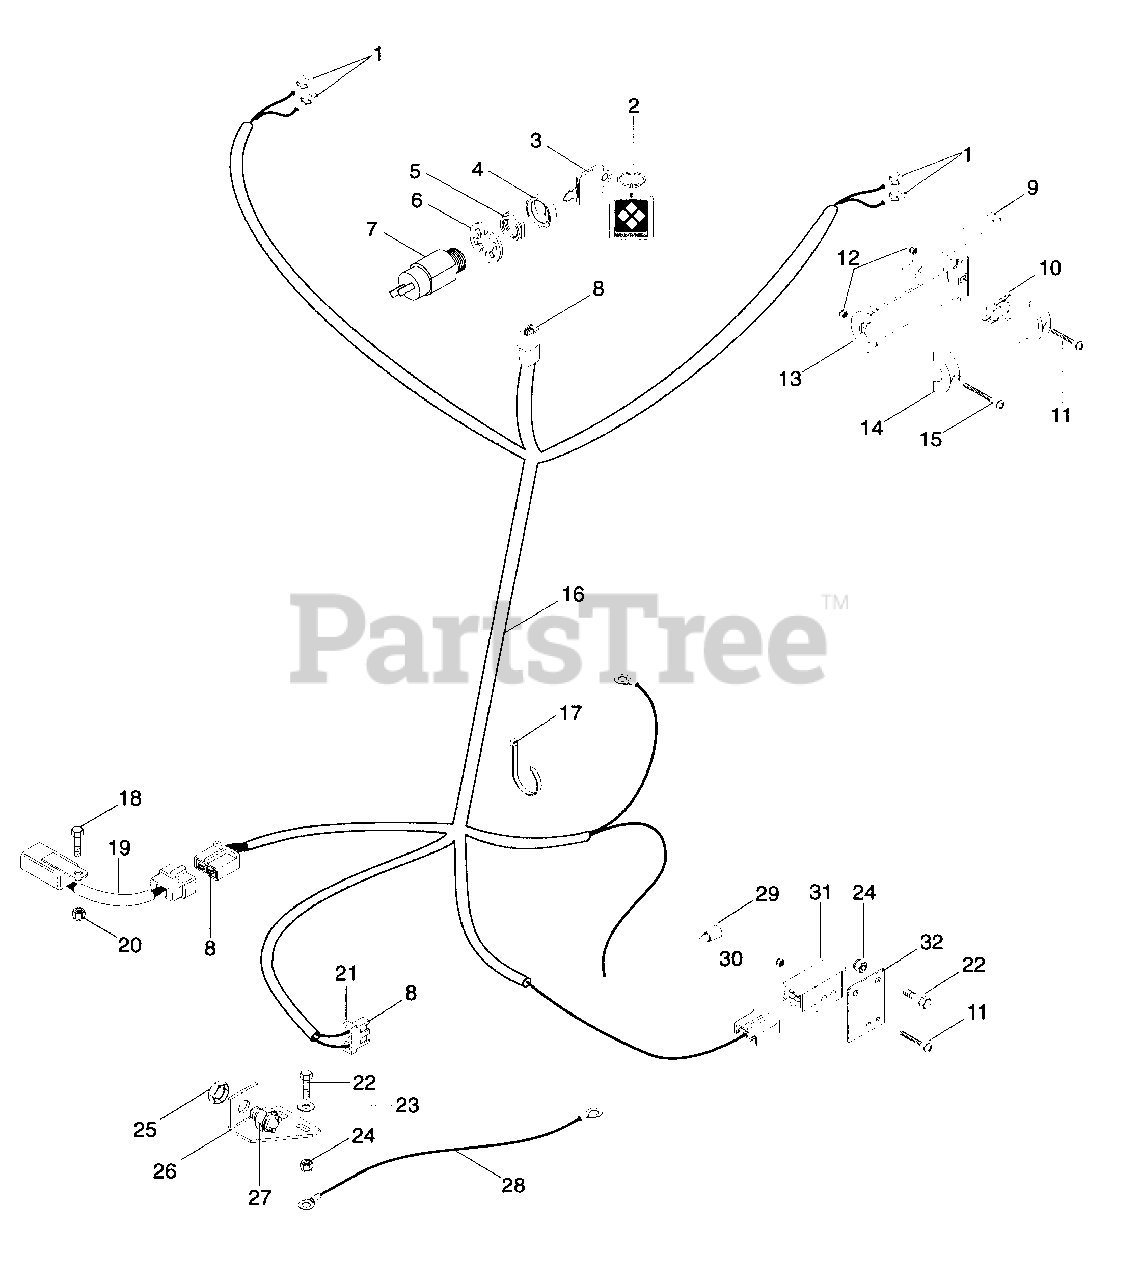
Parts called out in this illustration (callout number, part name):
1	Terminal, Female
2	Key Chain
3	Ignition Switch Key
4	Cap-Ignition Switch
5	Nut-Panel .625-32
6	Washer-Lock .625
7	Switch
8	Terminal
9	Lever
10	Switch
11	Screw-Machine 10-24 x .625
12	Nut-Locking 10-24 Nylon
13	Handle, Right Hand
14	Handle, Left Hand
15	Screw-Machine 10-24 x 1.50
16	Wire Harness, Pro-300 Recoil
17	Tie Wrap, Black
18	Bolt-Hex .25-20 x .75 Grade 5
19	Module
20	Nut-Locking-Nylon .250-20 w/Insert Grade 2
21	Connector, 2-Wire Switch
22	Bolt-Hex .25-20 x.75 Grade 5
23	Washer-Flat-Steel .281 x .625 x .065
24	Nut-Locking-Nylon .250-20 w/Insert Grade 2
25	Nut-Stamped .56-18
26	Bracket, Interlock Switch
27	Switch, Neutral Start, N.O.
28	Wire, Ground
29	Nut-Connector
30	Nut, Locking, 10-24, Nylon
31	Switch, Interlock
32	Bracket, Interlock Switch
